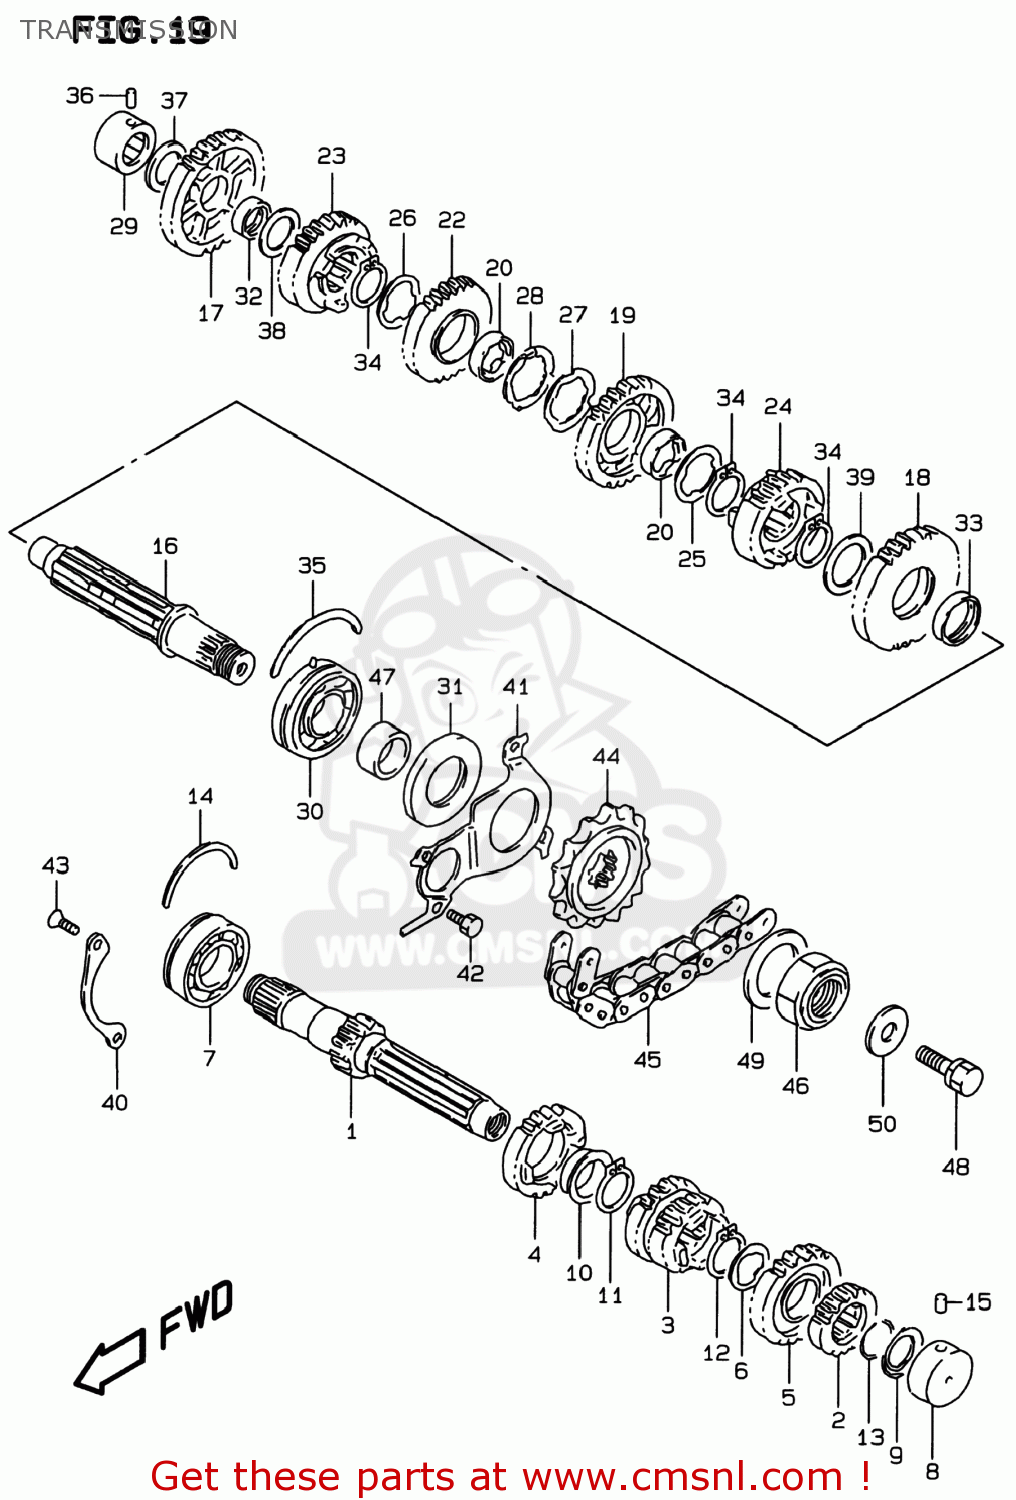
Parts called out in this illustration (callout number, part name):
1	SHAFT,COUNTER(NT:12)
2	GEAR,2ND DRIVE(NT:16)
3	GEAR,3RD & 4TH DRIVE(NT:17/20)
4	GEAR,5TH DRIVE(NT:22)
5	GEAR,6TH DRIVE(NT:21)
6	WASHER,LOCK
7	BEARING(25X62X17)
8	BEARING(20X34X17.5)
9	SEAL,OIL(20X31.2X2.7)
10	BUSHING
11	RING,SNAP
12	RING,SNAP
13	CIRCLIP
14	C RING
15	PIN
16	SHAFT,DRIVE
17	GEAR,1ST DRIVEN(NT:37)
18	GEAR,2ND DRIVEN(NT:33)
19	GEAR,3RD DRIVEN(NT:28)
20	BUSH
21	BUSH
22	GEAR,4TH DRIVEN(NT:28)
23	GEAR,5TH DRIVEN(NT:27)
24	GEAR,6TH DRIVEN(NT:23)
25	WASHER,LOCK
26	WASHER,LOCK
27	WASHER,LOCK
28	WASHER
29	BEARING(20X34X20)
30	BEARING(25X62X21.6)
31	SEAL,OIL(34X62X6)
32	BUSH(22X26X9)
33	BUSH(28X32X9.5)
34	CIRCLIP
35	C RING
36	PIN
37	WASHER
38	WASHER
39	SHIM(28X38X1)
40	RETAINER,CNTR SHAFT BEARING
41	RETAINER,DRIVE SHAFT OIL SEAL
42	BOLT
43	SCREW ,6X16
44	SPROCKET,ENGINE(NT:15)
45	CHAIN,DRIVE(112LE)
46	NUT
47	SPACER(25X34X17.5)
48	BOLT
49	WASHER,THRUST
50	WASHER
